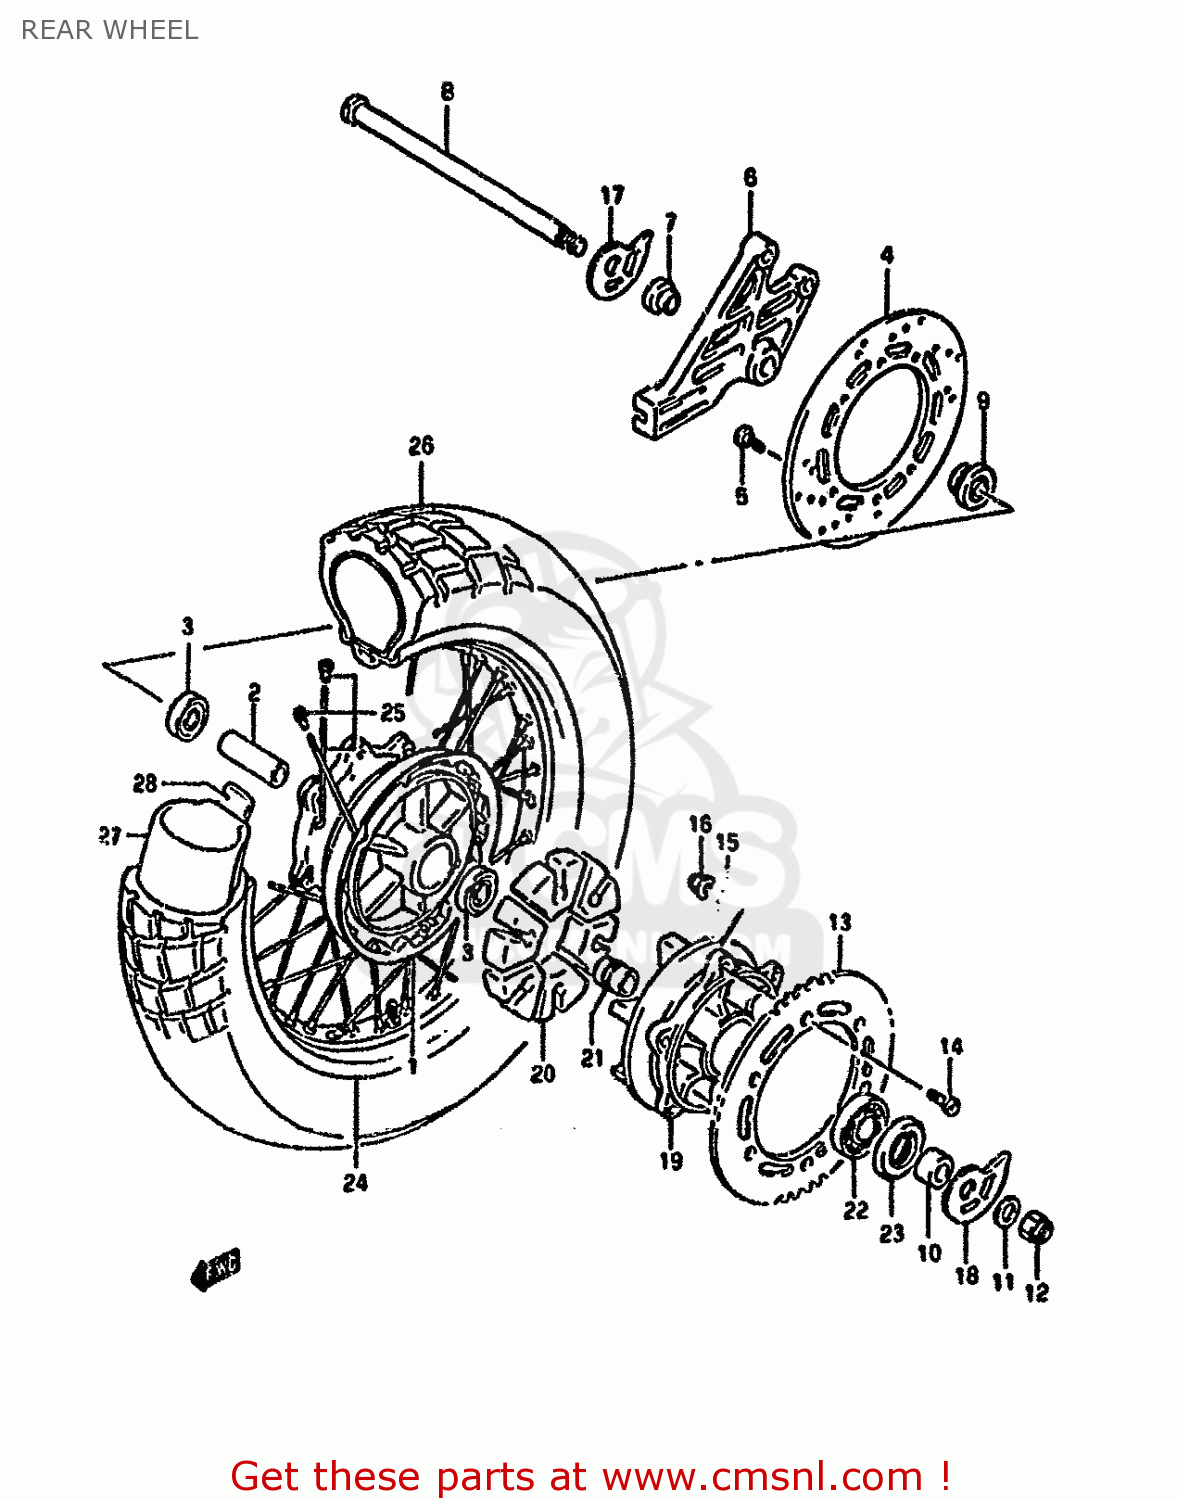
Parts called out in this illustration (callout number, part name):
1	HUB COMP,REAR WHEEL
2	SPACER(17.5X25X78)
3	BEARING
4	DISC,RR BRAKE
5	BOLT,BRAKE DISC
6	BRACKET,RR CALIPER
7	SPACER (17X21X10)
8	AXLE,RR
9	SPACER,RR AXLE,L
10	SPACER(17X33X22.4)
11	WASHER (17X30X3.2)
12	NUT
13	SPROCKET,REAR
14	BOLT(8X30.5)
15	WASHER
16	NUT
17	ADJUSTER,CHAIN,R
18	ADJUSTER,CHAIN,L
19	DRUM,REAR SPROCKET
20	ABSORBER,RR HUB SHOCK
21	RETAINER,RR SPROCKET DRUM
22	BEARING(25X62X17)
23	SEAL,OIL(33X62X7)
24	RIM,RR WHEEL(17XMT2.50)
25	SPOKE SET,RR
26	TIRE,REAR 120/90-17 64
27	TUBE ASSEMBLY,WHEEL,INNER
28	PROTECTOR,WHL INR TUBE
